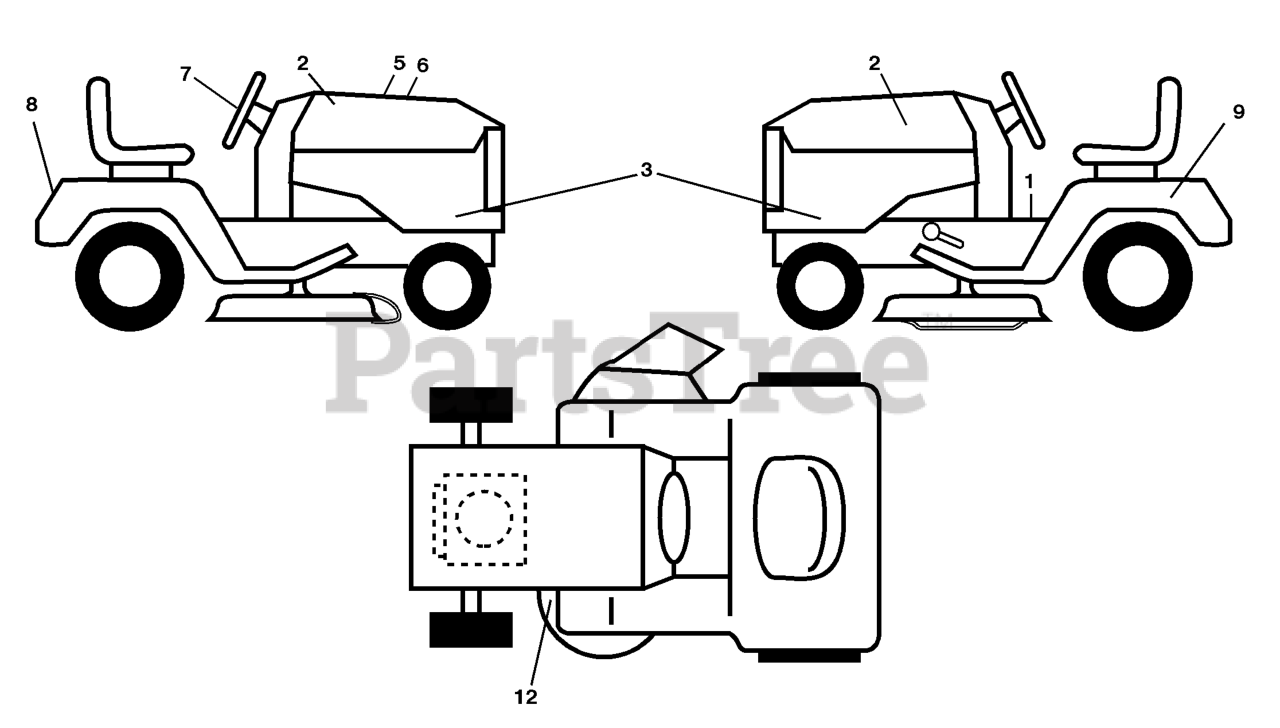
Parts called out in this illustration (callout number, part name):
1	DECAL.FENDER.WARNING
2	DECAL.HOOD.LOGO.HUSQVARNA
3	DECAL, HOOD PANEL SD
5	DECAL HOOD CUST. RESP.
6	DECAL.RPL.KH.SV600.TLW.46"
7	DECAL.WHEEL.STRG.LGN.H
8	DECAL.FENDER
9	DECAL BTRY SYMBOLS
12	DECAL V BELT SCHEMATIC
12	DECAL.BYPASS.FENDER.CRD.LT.YT
12	PAD, FOOTREST, LH
12	PAD, FOOTREST, RH
12	DECAL.PDL CNTRL.HYD.LOWES.BLUE
12	Manual, Owner's
